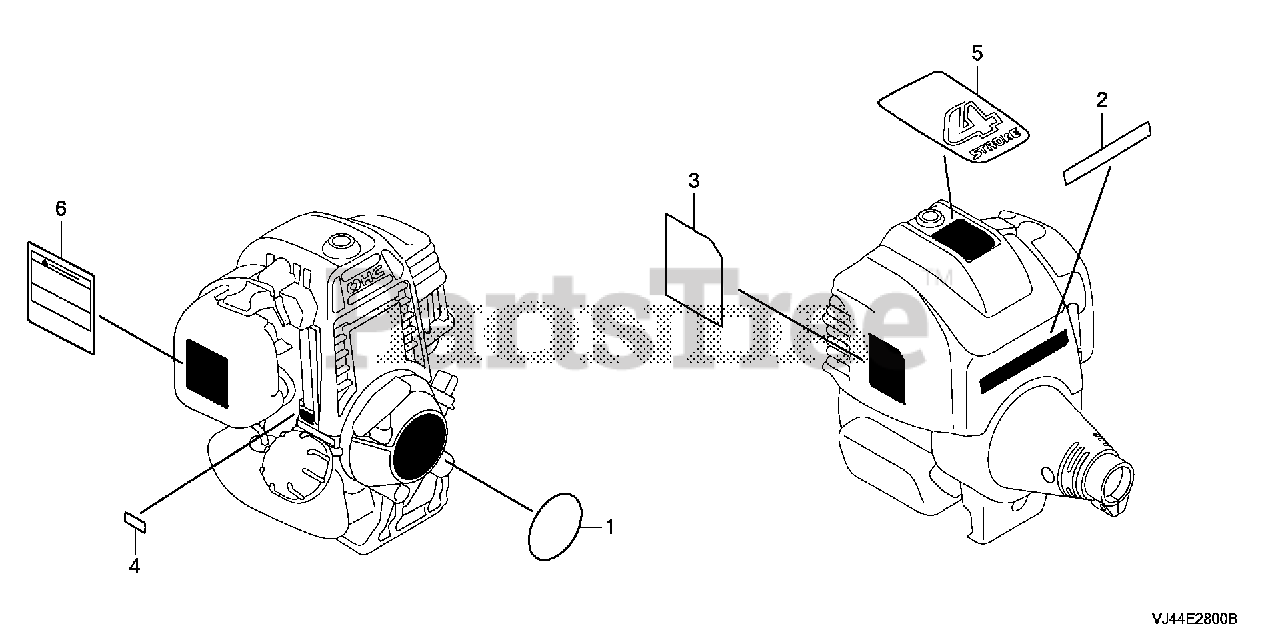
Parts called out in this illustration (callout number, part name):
1	MARK, EMBLEM
3	LABEL, SPARK WARNING
4	MARK, TYPE (GY1)
5	MARK (4-STROKE)
6	MARK, OPERATOR CAUTION (ENGLISH)
